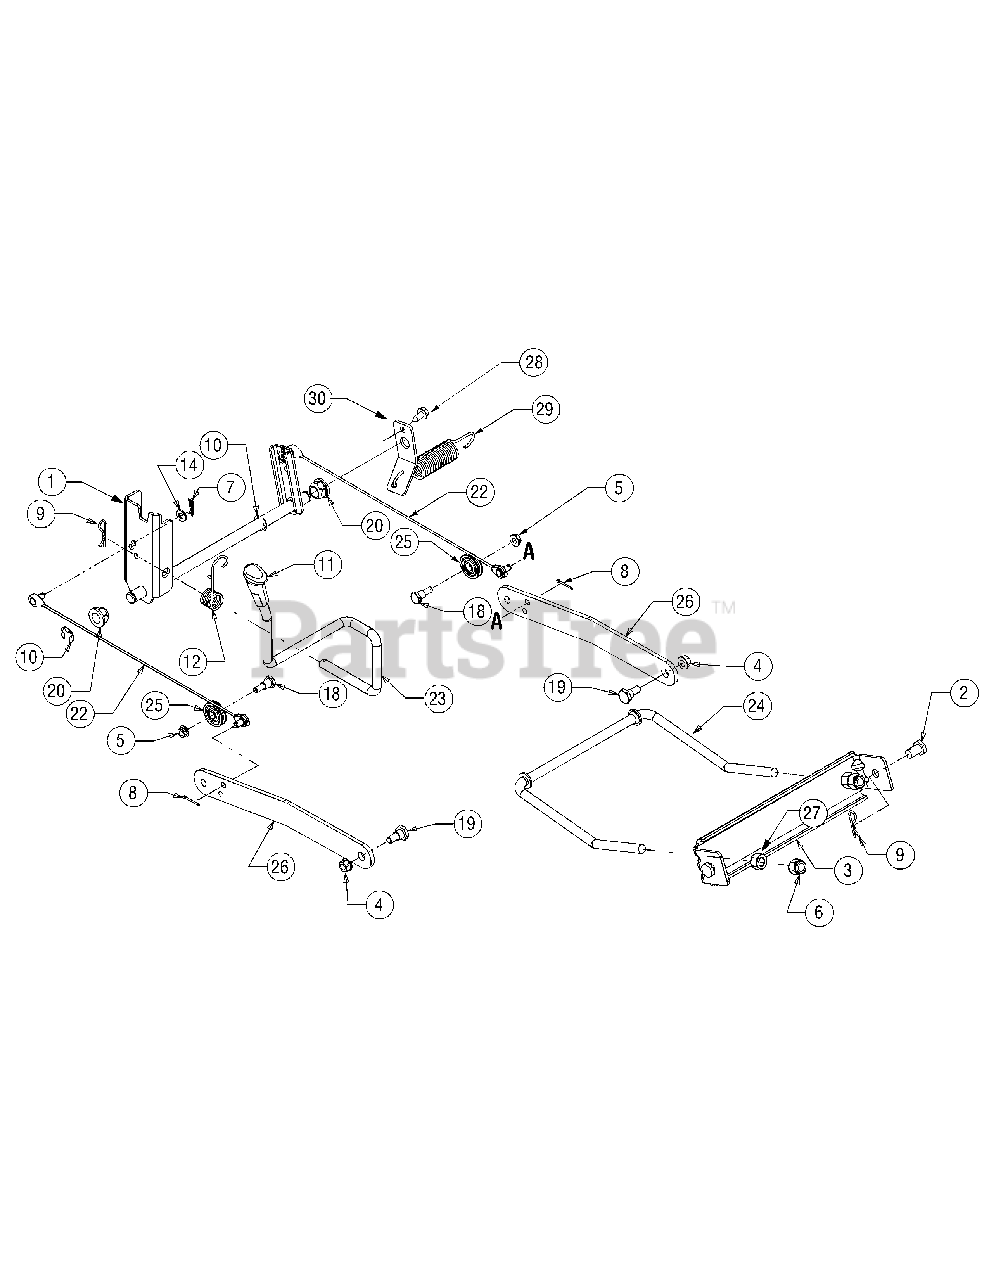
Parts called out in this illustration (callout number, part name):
4	Nut, Nylon Lock, 3/8-16
5	Nut, Nylon Lock, 5/16-18, Gr5
6	Nut, Hex Lock, 1/2-13, Gr8, Nylon
7	Pin, Cotter, .072 Dia. x 1.13 Lg
8	Pin, Cotter, 3/32, 1.0
9	Pin, Click, .092 x 1.64 Lg
10	E-ring, .625 Dia. Shaft
11	Grip, Handle
12	Spring, Torsion
18	Screw, Hex Cap, 5/16-18x.620 Gr2
19	Shoulder Screw, 3/8-16
20	Bearing, Hex Flange
22	Cable, Lift, 16.16 Lg
23	Handle, Lift
24	Rod, Deck .5" Dia.
25	Pulley, Roller
27	Nut, Hex, 1/2-13
28	Screw, Self-tapping, 5/16-12, 0.75
29	Spring, 1.01 x 6.5
30	Bracket, Lift
